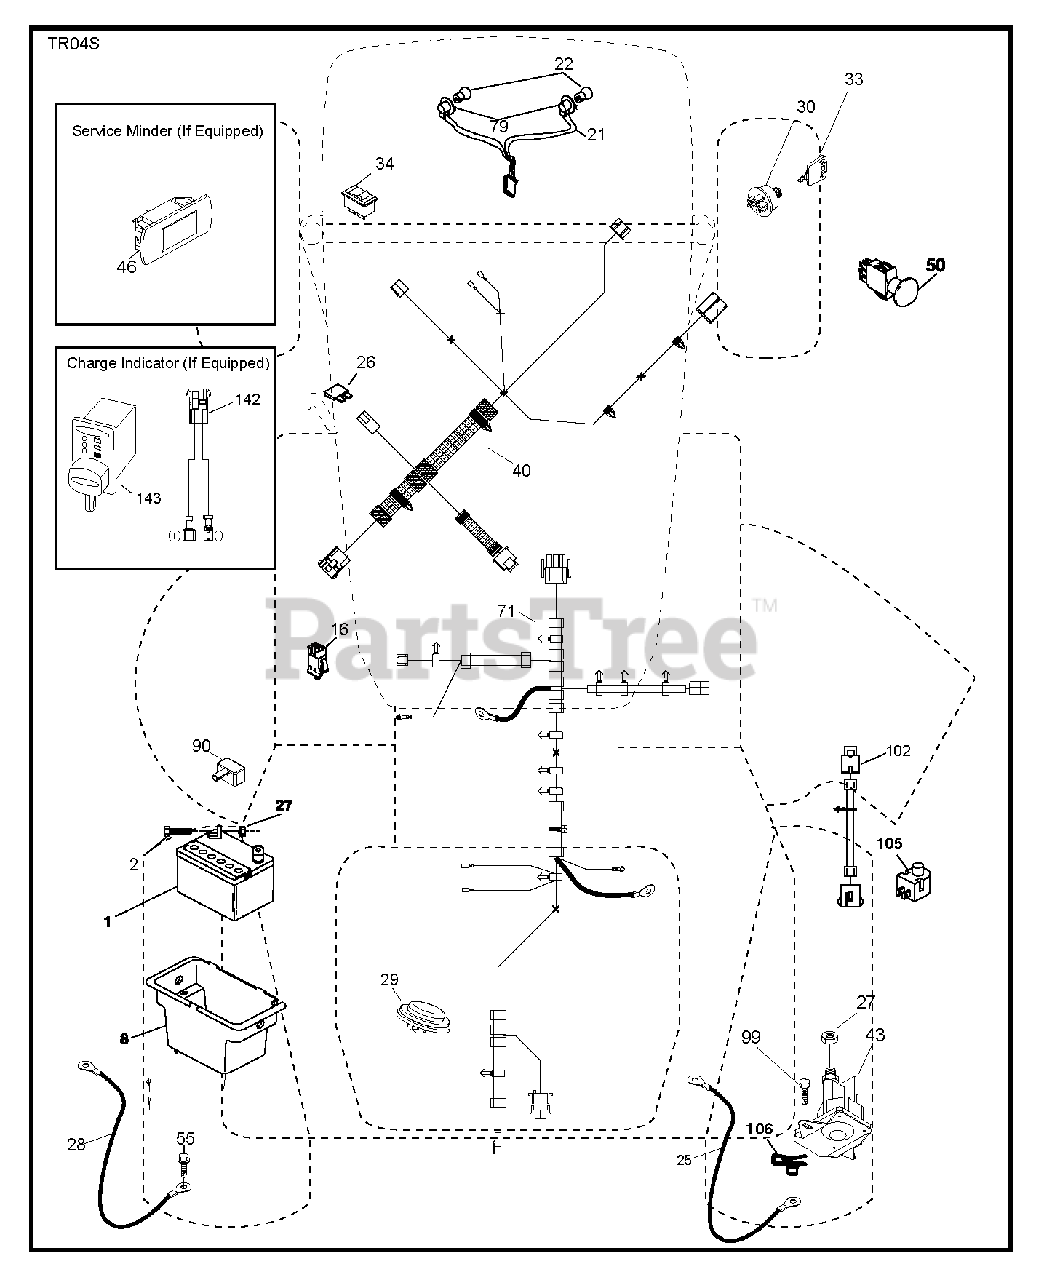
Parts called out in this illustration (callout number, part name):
1	Battery, Dry 30 Amp
2	BOLT.HEX.1/4.X.3/4.DICHROMATE
8	BOX.BATTERY.MNT.REAR.L
16	SWITCH INTERLOOK PUSH-IN
21	HARNESS.LIGHT W/4152J BULBS
25	CABLE.BATT.RED.8GA.17
26	FUSE 20AMP
27	NUT
28	CABLE.GROUND.REAR.BATTERY.8G
29	SWITCH.SEAT.DELTA.OPC.
30	SWITCH.IGN.DELTA.W.LGH.ROS
33	KEY.CHAIN.BLISTER.PACK.GEN.USA
40	HARNESS.TEX.DASH.ELEC.REAR BAT
43	SOLENOID.STARTER.BRASS.PLUNGER
46	GUAGE.SRVCMNDR.HRMTR.
50	SWITCH.PTO.8TERMINAL.STD.BLK
55	SCREW 5/16"
71	HARNESS.CHASSIS.RRBATT.RDYSTRT
79	BULB HOLDER ASM.
90	COVER.TERMINAL.BATTERY
99	SCREW HEXWSHR 1/4-20X3/4
102	HARNESS PIGTAIL PCH TEX ROS
105	REVERSE SWITCH
106	1/4-20 U NUT
